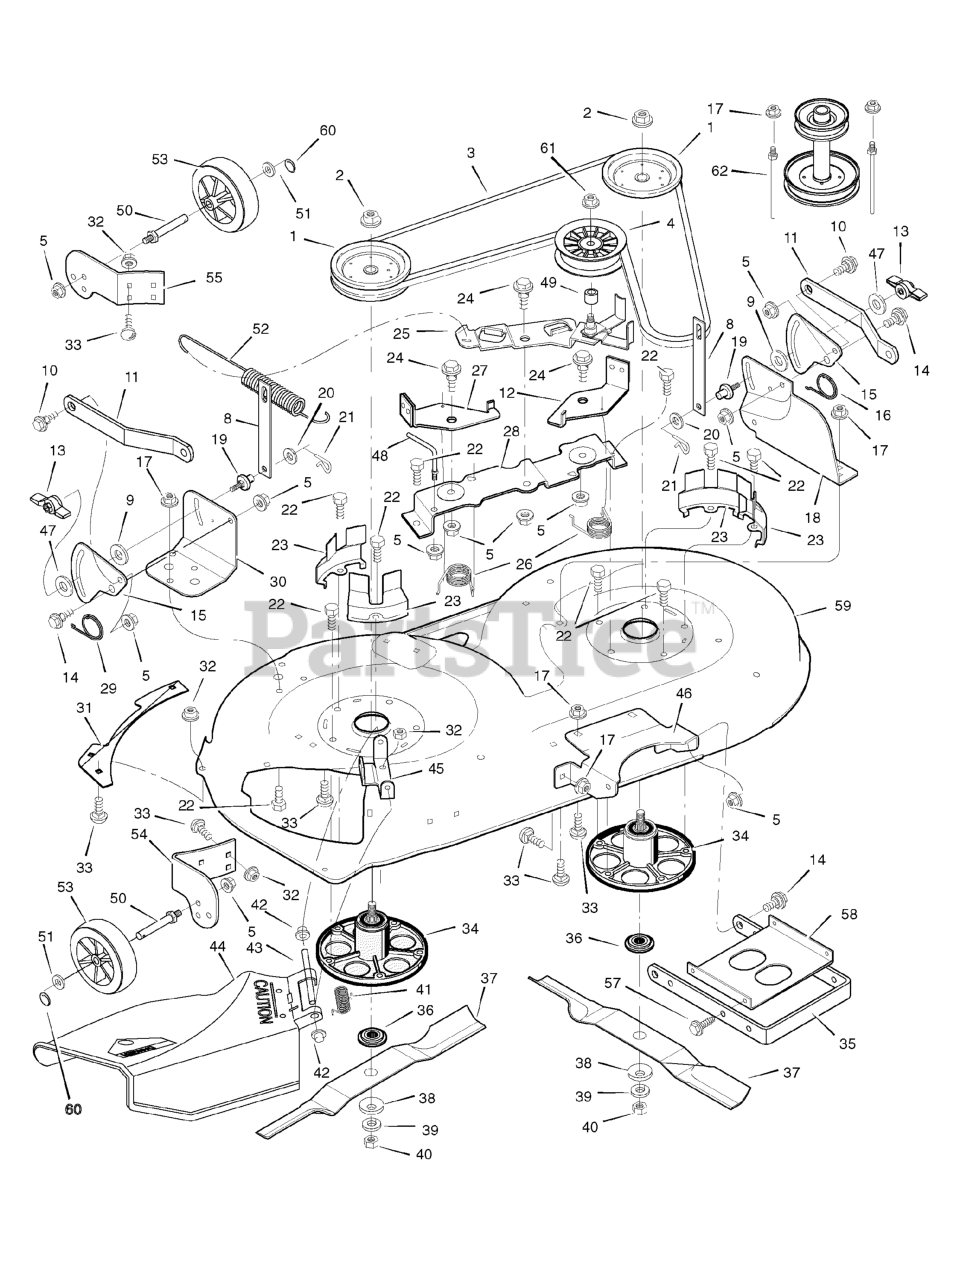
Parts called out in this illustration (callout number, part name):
1	Pulley, Jackshaft
2	Nut, Hex
3	Belt, Mower Drive
4	Pulley, Idler
5	Nut, Flange
8	Link, Lift
9	Pad, Friction
10	Bolt, Shoulder
11	Bracket, Suspension
12	Pad Assembly, Left Brake
13	Knob
14	Bolt, Shoulder
15	Plate, Suspension
17	Nut, Flange
18	Bracket, Suspension
19	Pin, Hanger
21	Pin, Hair
22	Bolt
23	Cover, Pulley
24	Bolt, Shoulder
25	Arm, Idler
27	Pad Assembly, Right Brake
28	Bracket, Brake
30	Bracket, Suspension
32	Nut, Flange
33	Bolt, Carriage
34	Mandrell Housing
35	Bracket, Suspension
36	Adapter, Blade
42	Cap, Push On
43	ROD, Deflector
44	Deflector Assembly
45	Bracket, Deflector Hinge
46	Bracket, Front Hanger
48	Guide, Belt
50	BOLT, Gauge Wheel
52	Spring, Extension
53	Wheel, Gage
54	Bracket, Right Wheel
55	Bracket, Left Wheel
59	Housing, Blade
60	Ring, Locking
61	Nut, Flange
62	Guide, Belt
